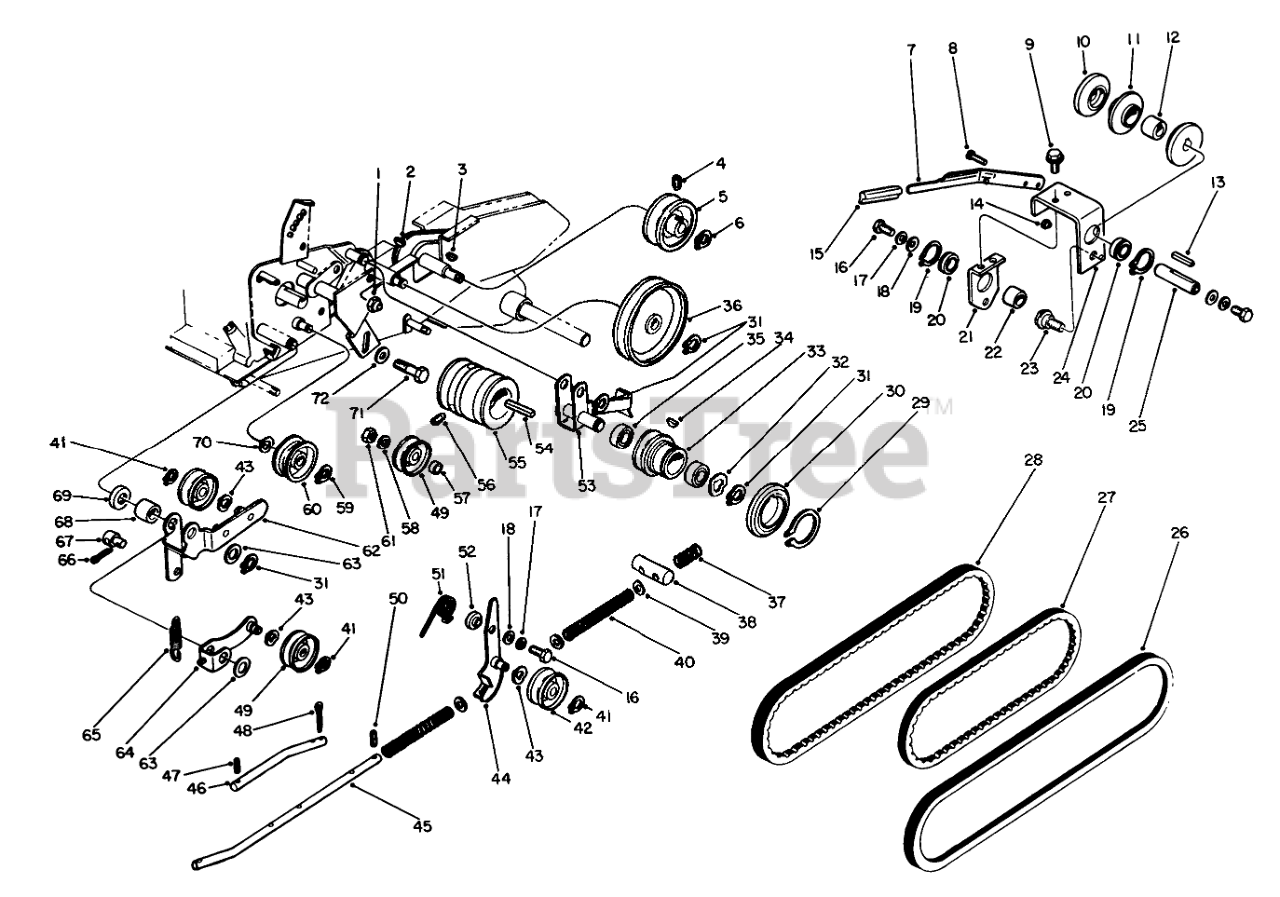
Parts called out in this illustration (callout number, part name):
1	NUT-LOCK, CONE
2	Key-Woodruff
4	SCREW-SET, HSH
5	Pulley-Tine Drive
6	Retaining Ring
7	Handle-Speed Adjustment
8	Machine Screw
9	Thread Forming Screw
10	Fixed Sheave
11	Sliding Sheave
12	Spacer-Sheave
13	Key-Square
14	NUT-LOCK, SIDE
16	SCREW-HH
17	WASHER-LOCK
18	WASHER-PLAIN
19	Retaining Ring
20	Bearing
21	Bracket
22	Spacer
23	Shoulder Bolt
24	Pivot Bracket
25	Idler Shaft
26	Traction Drive Belt
27	Belt-Reverse
28	Tine Drive Belt
29	Retaining Ring
30	Drive Ring Assembly
31	RING-SNAP, EXTERNAL
32	Wave Washer
33	Drive Pulley-Reverse
34	KEY-WOODRUFF
35	Bearing
36	Pulley-Traction Drive
37	Spring
38	Swivel
39	WASHER-FLAT
40	Spring-Traction Drive
41	Retaining Ring
42	Idler-Drive
43	Wave Washer
44	Idler Arm-Tine Drive
45	Rod-Clutch
46	Rod Reverse
47	PIN-SPRING
48	PIN-COTTER
49	Idler-Reverse
50	Pin
51	Spring
52	Pivot Bushing
53	Arm-Reverse
54	Key-Square
55	Engine Pulley
56	SCREW-SET
57	Spacer-Drive Idler
58	WASHER-LOCK
59	Retaining Ring
60	Idler-Flat
61	NUT-HEX
62	Idler Arm-Forward
63	Washer
64	Idler Arm-Reverse
65	Spring-Reverse
66	PIN-COTTER
67	Trunnion
68	Spacer-Idler Arm
69	Spacer-Cup
70	Wave Washer
71	SCREW-HH
72	WASHER-FLAT
